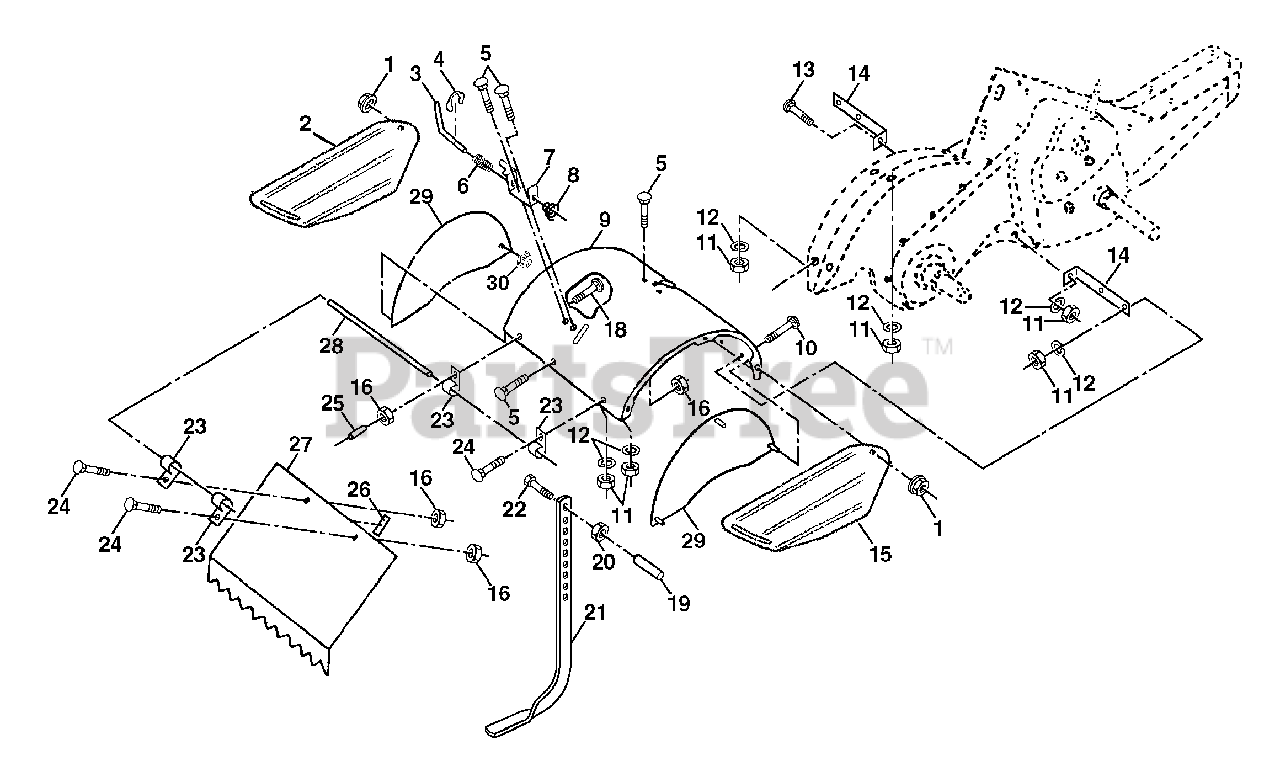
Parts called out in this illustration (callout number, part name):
1	Nut, Flange 5/16-18
2	Shield, Side, Outer L. H.
3	Pin, Stake, Depth
4	Ring, Klip
5	Bolt, Carriage 5/16-18 x 3/4 Gr. 5
7	Bracket, Latch
8	Spring, Depth Stake
9	Shield, Tine
10	Bolt, Carriage 5/16-18 UNC x 1
11	Nut, Hex 5/16-18
12	Washer, Lock 5/16
13	Bolt, Carriage 5/16-18 x 1-1/4
14	Bracket, Shield Tine
15	Shield, Side, Outer R.H.
16	Nut, Keps Hex 1/4-20
18	Bolt, Carriage 1/4-20 x 1-1/4 Gr. 5
20	Nut, Hex 3/8-16
21	Stake, Depth
22	Bolt, Hex 3/8-16 x 2
24	Bolt, Carriage 1/4-20 x 1/2 Gr. 5
25	Cap, Vinyl
26	Pad, Idler
27	Shield, Leveling
28	Pin, Hinge
29	Shield, Side
30	Locknut, Flange 5/16-18
